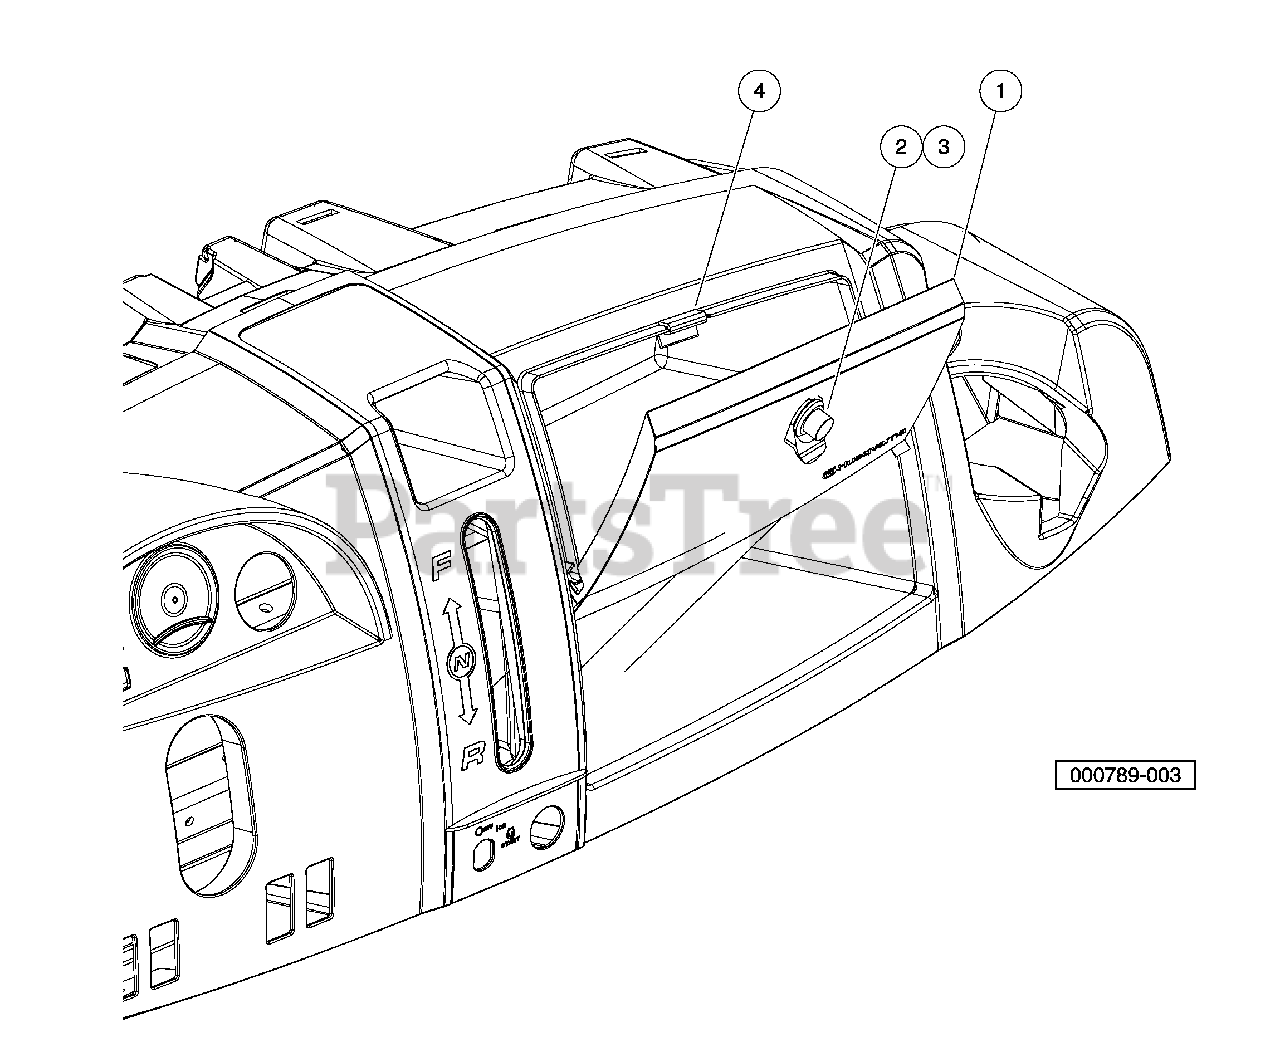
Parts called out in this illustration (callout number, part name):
1	Cover, Storage, Dash, Awd, Cci
2	Latch, Push Close
3	Latch, Push Close W/ Key
4	Keeper, Latch, Push Close
